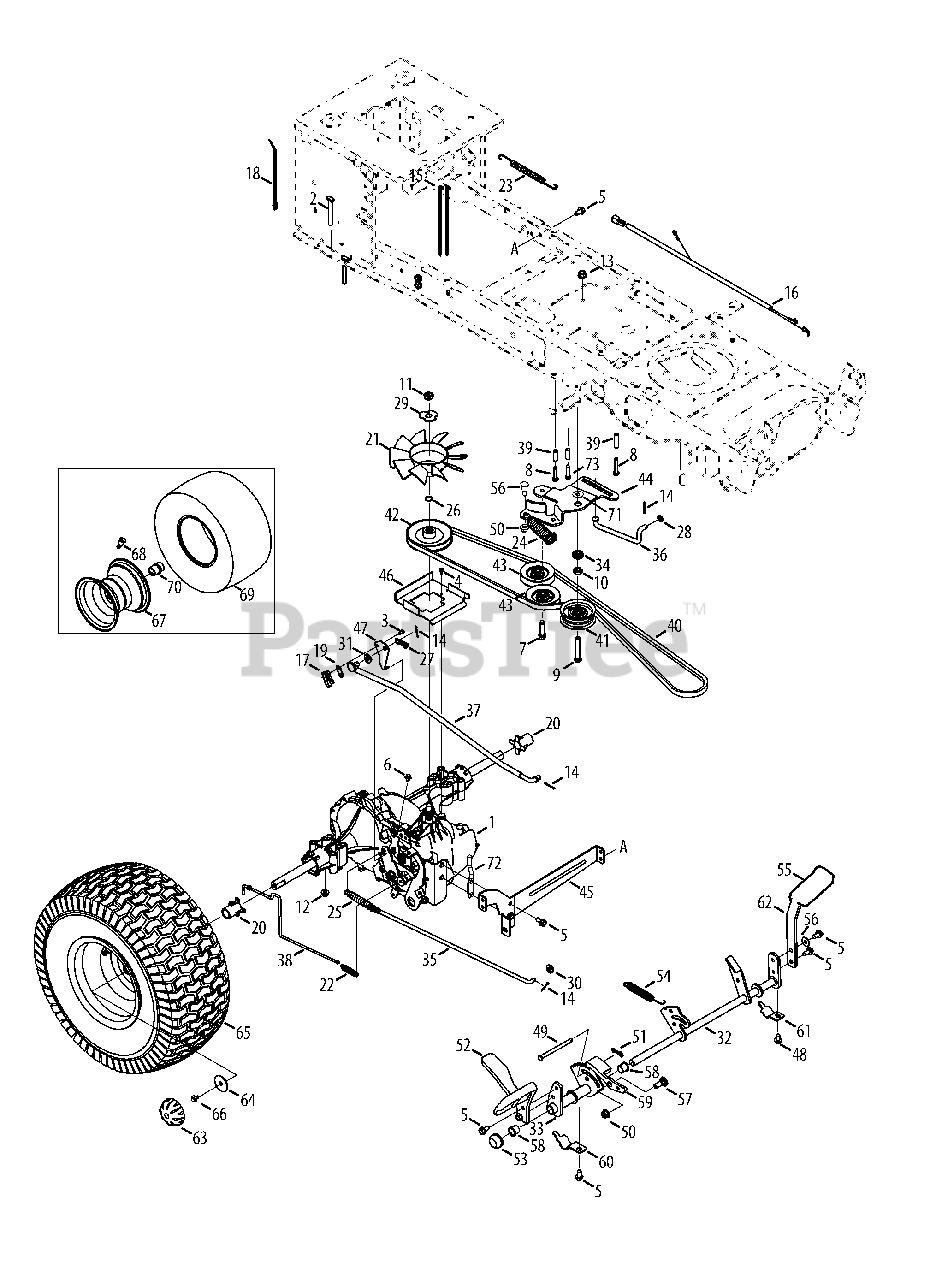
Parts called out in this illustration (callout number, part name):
1	Hydro Transmission
2	Hex Screw, 5/16-18:2.75
3	Screw, #8-18:0.500
4	Screw, #10-16:0.500
5	Taptite Screw, 5/16-18:.750
6	Taptite Screw, 1/4-20:0.375
7	Screw, Sems, 3/8-16, 1.500
8	Taptite Screw, 1/4-20:1.625
9	Hex Screw, 3/8-16:2.25
10	Jam Nut, 7/16-20
11	Nut, Jamlock, 1/2-20
12	Flangelock Nut, 5/16-18
13	Flangelock Nut, 3/8-16
14	Cotter Pin, 3/32:1.0
15	Cable Tie, 3/16 X .05 X 7.4
16	Jumper Harness
17	Short Spring Switch
18	Push Mount Cable Tie 7.5 LG
19	Insulator Nut Plate
20	Sleeve, .765 ID x 1.500 LG
22	Extension Spring, .48 OD X 2.03
23	Extension Spring, .500 DIA X 12.6 LG
24	Extension Spring, 1.00 DIA X 4.75
25	Extension Spring, .59 OD X 4.00 LG
26	Wire Ring
27	Extension Spring, .375 OD X 1.44 LG
28	Washer, Flat, .330 X .630 X .0635
29	Washer, Lock, TRANS HYDRO
30	Washer, Flat, .344 X .750 X .120
31	Washer, Flat, .407X.812X.135:HT
32	Brake Control Assembly
33	Hydro Pedal Bracket Assembly
34	Spacer, Shoulder, 1.375 X .380 X .183
35	Rod, Brake, Hydro
36	Rod, Transmission, Footpedal Bypass
37	Rod, Control, Hydro
38	Rod, Hydro Bypass
39	Spacer, .260 X .372 X 1.420 LG
40	Belt, V Type, Poly
41	Pulley, Idler, Flat 2.75 OD
42	Pulley, Input, 4.13 DIA
43	Pulley, Idler, V-Type x 3.06
44	Bracket, Idler, Center Double
45	Bracket, Mount, Hydro
46	Bracket, Support, Belt Disengage
47	Switch Actuator Bracket
48	Taptite Screw, 5/16-18:0.625
49	Clevis Pin, 5/16 x 3.985
50	Flangelock Nut, 3/8-16
51	Bow-Tie Cotter Pin
52	Control Pedal
54	Extension Spring, .63 DIA x 4.95 LG
55	Brake Pedal Pad
56	Scr, Shldr, .50 x .685 3/8-16
57	Shoulder Bolt, .500 x .270:3/8-16
58	Flange Bearing, .630 ID x .695 OD x .60
59	Cruise Latch
60	Pedal Support Bracket
61	Pedal Support Bracket, 5/8
62	Brake Pedal Bracket
63	Hub Cap
64	Washer, Flat, .350 x 1.59 x .062
65	Wheel Assembly
66	Screw, 5/16-24 x .750
67	Rim Assembly, Plastic Bead, 46"
68	Tubeless Air Valve
69	Tire, 20 x 8 x 8
71	Washer, Flat, .385 x 1.0 x .030
72	Belt Keeper Rod
73	Screw, Self Tapping, 1/4-20 x 1.75
